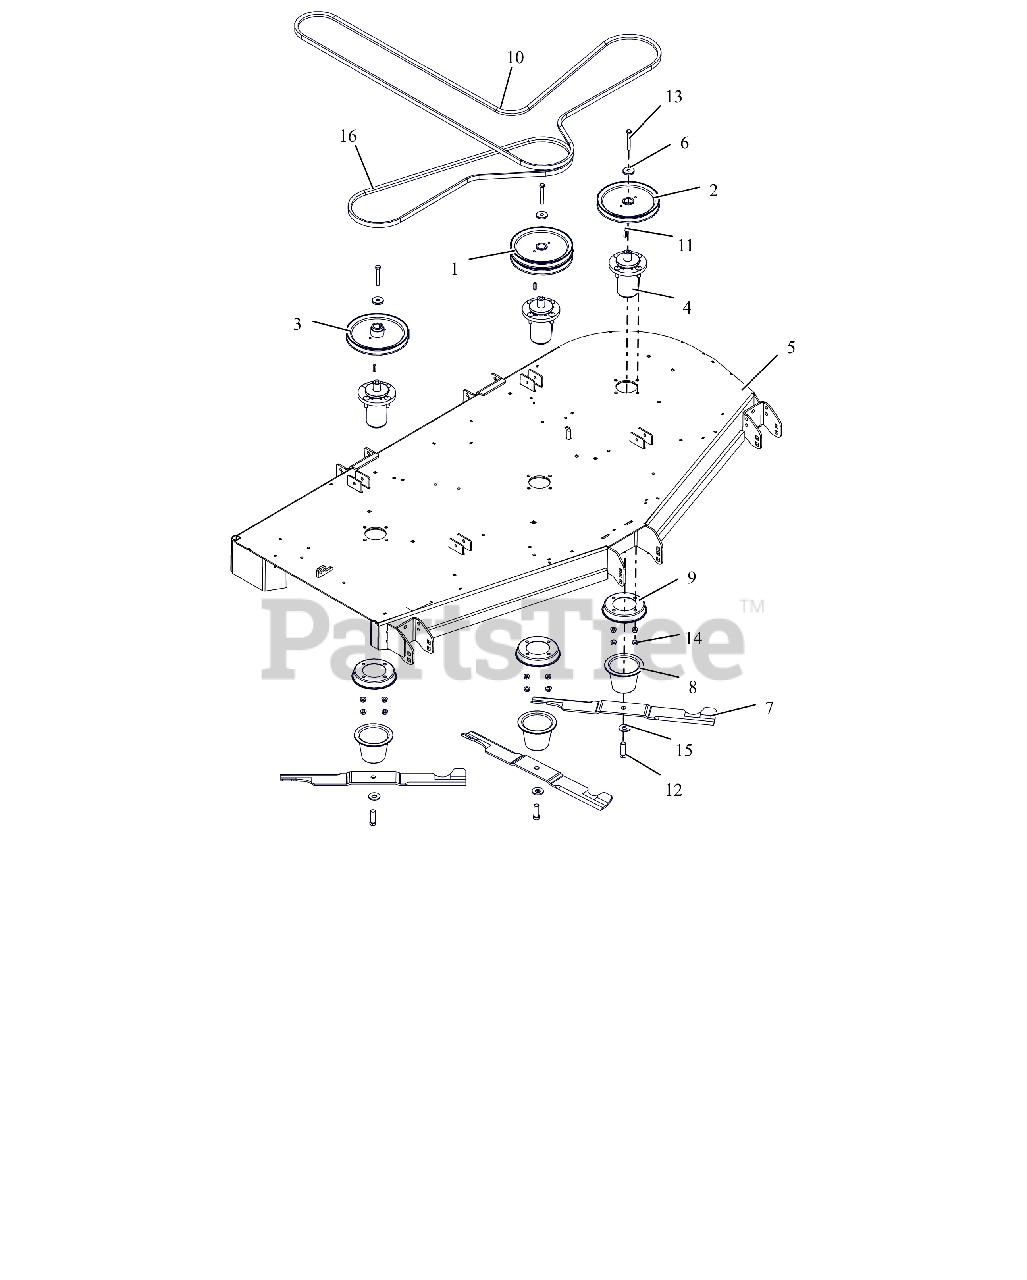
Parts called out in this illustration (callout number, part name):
1	SHEAVE-DOUBLE 1.00"IDX8.25"OD
2	SHEAVE-SINGLE 1.00"IDX8.25"OD
3	SHV-SINGLE 1.00"ID X 8.25"OD
4	ASM, MAINT FREE ALUM SPINDLE
5	72"SIDE DISCH DECK WMT W/SAFE
6	RETAINER, SHEAVE
7	BLADE, 72"
8	GUARD, SPINDLE LOWER
9	GUARD, SPINDLE TOP
10	V-BELT, HB WRAPPED
11	KEY, SQ .25X.25X1.00 RC 40-50
12	BLT, HEX .62-18X1.75 G8 ZCC
13	BLT, HEX .38-16X2.75 G8 ZCC
14	NUT-LK-CTR-FLG .375-16 GF ZCC
15	WSHR-BLVL .669X1.535X.138
16	V-BELT, B-COGGED
